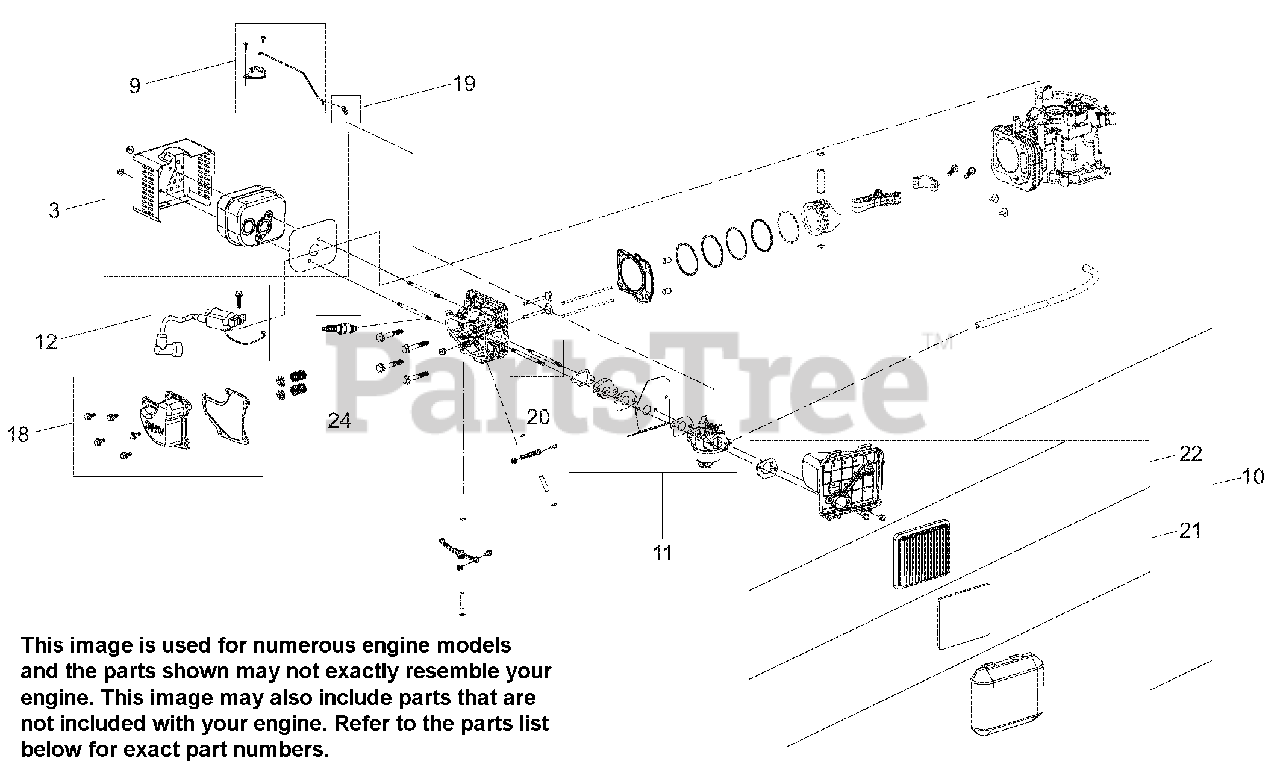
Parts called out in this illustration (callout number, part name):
1	KIT, AIR VANE CHOKE - SVC
2	GOVERNOR ARM KIT
3	KIT, MUFFLER AND SHIELD - SVC
4	FLYWHEEL AND FAN KIT - RECOIL START
5	KIT, BRAKE ASM RECOIL - SVC
6	KIT BRAKE ASSEMBLY - ELECTRIC
7	KIT, ARIENS STYLE - SVC
8	KIT, FLYWHEEL SHIELD - SVC
9	KIT, THERMAL CHOKE CONTROL-SVC
10	KIT, AIR CLEANER ASM - SVC
11	KIT, CARBURETOR COMPLETE - SVC
12	KIT, IGNITION COIL - SVC
13	KIT, SEAL AND GASKET - SVC
14	FLYWHEEL AND FAN KIT - ELECTRIC START
16	STARTER KIT - ELECTRIC START
17	KIT, WIRE HARNESS - SVC
18	KIT, VALVE COVER - SVC
19	LOCK, THROTTLE - SVC
20	STUD, INTAKE - SVC
21	ELEMENT, AIR CLEANER
22	FILTER, AIR - LONCIN 160CC
23	KIT, FUEL LINE W/FILTER - SVC
24	SPARK PLUG, LONCIN 160CC
25	DIPSTICK, OIL - SVC
26	CAP, FUEL - SVC
27	ASM, FUEL TANK W/HARDWARE
28	KIT, RECOIL - SVC
29	ENGINE, SERVICE, AC SERIES
29	ENGINE, SERVICE, AC SERIES, ELEC
30	KIT, GOVERNOR ARM (BBC)
30	KILL SWITCH, ENGINE, BBC
31	KIT, FLYWHEEL AND FAN (BBC)
